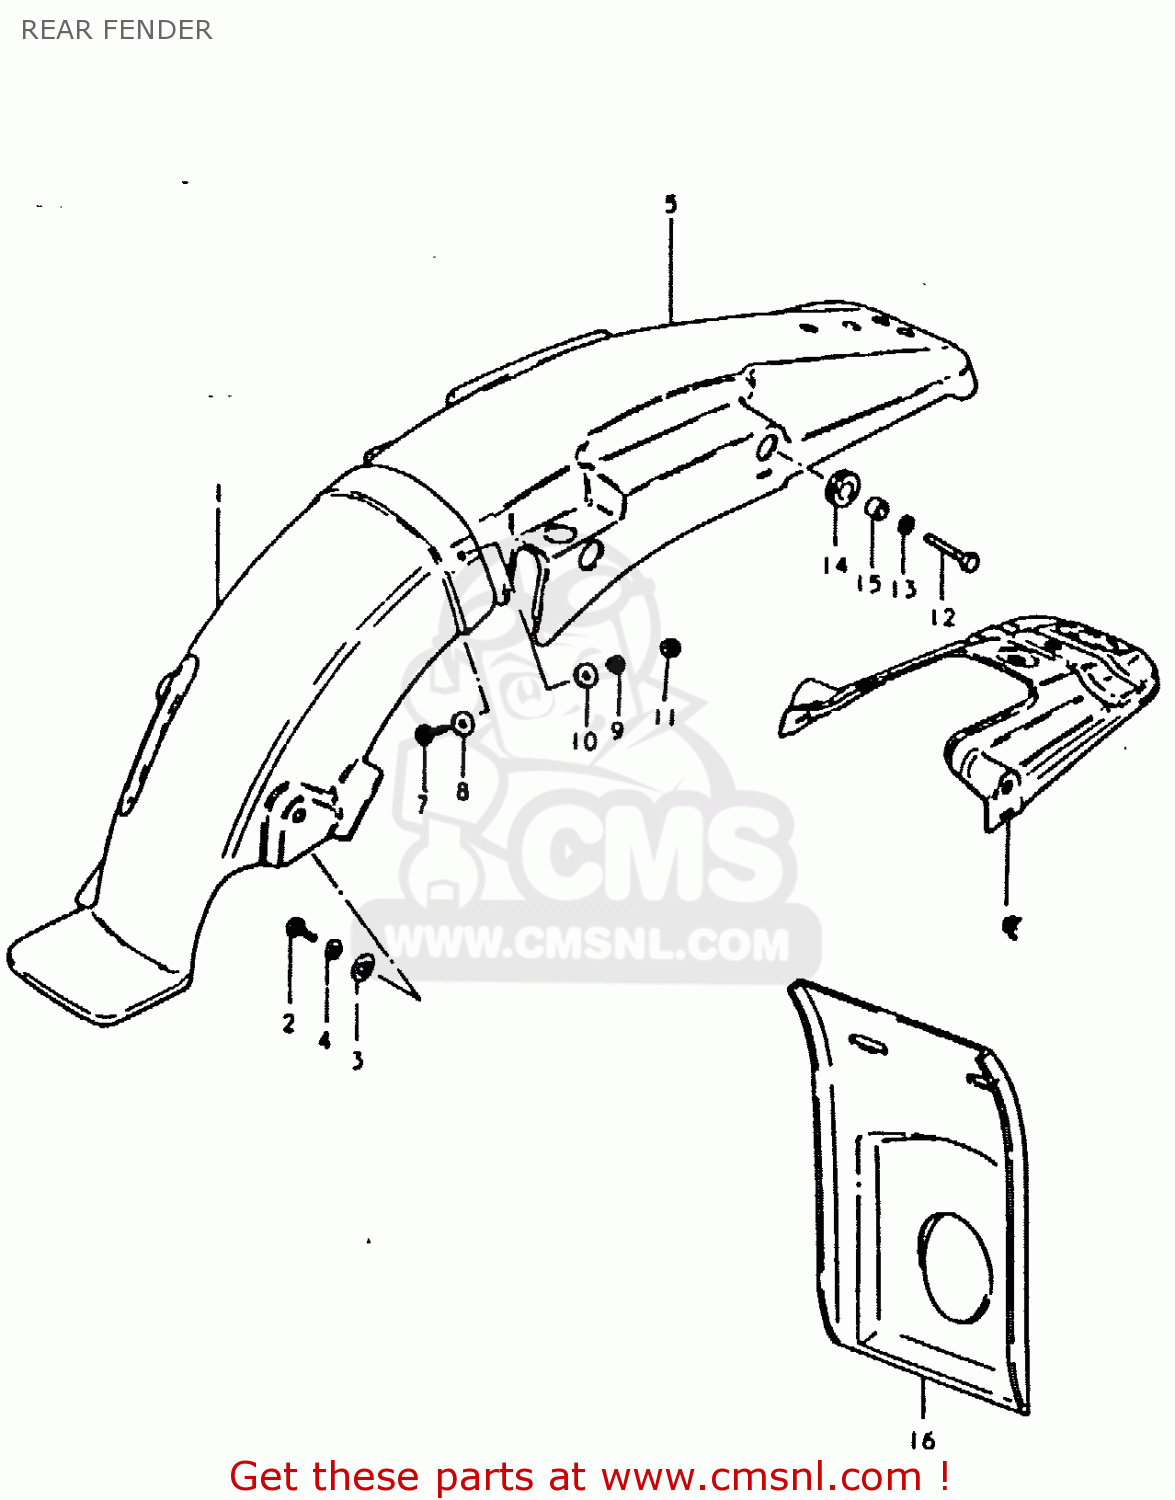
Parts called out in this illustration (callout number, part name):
1	BODY,REAR FENDER,FRONT
2	BOLT, UPPER
3	WASHER
4	LOCK WASHER
5	FENDER, REAR
6	REINFORCEMENT
7	BOLT
8	WASHER (5.5X16X1.2)
9	LOCK WASHER
10	WASHER(5.2X16X1)
11	NUT
12	BOLT (8X30)
13	LOCK WASHER
14	CUSHION
15	SPACER (8.2X12X7.5)
16	FLAP,RR FENDER MUD
